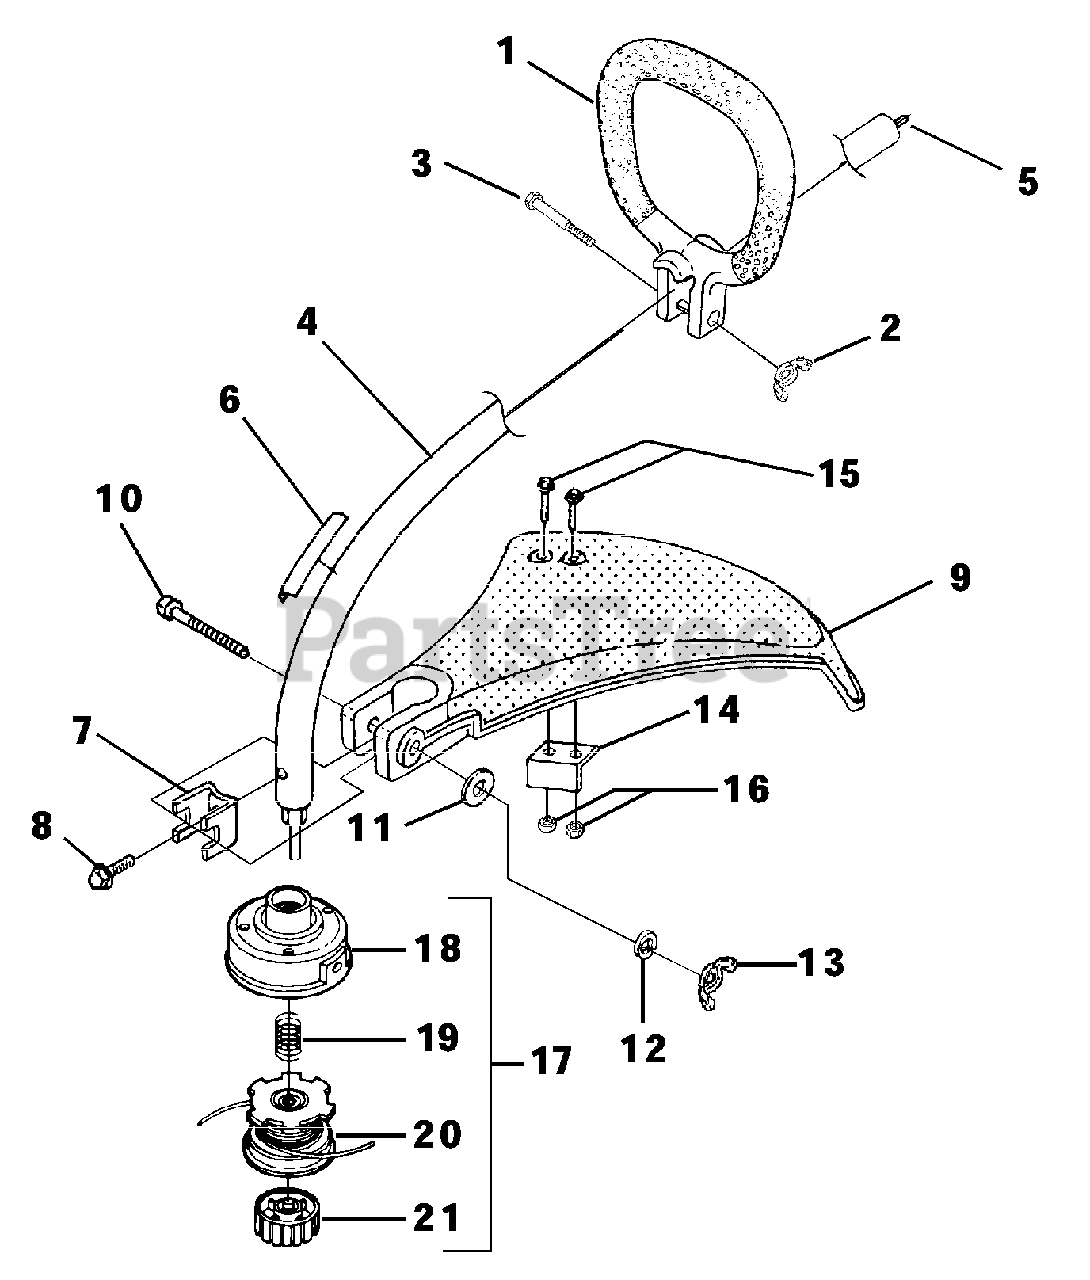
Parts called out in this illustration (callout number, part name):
1	HANDLE ASSY.-Front
2	NUT-Wing, Washer Faced (1/4-20)
3	SCREW-Cap Hex Hd.
4	DRIVESHAFT HOUSING ASSY.
5	SHAFT-Flexible
6	DECAL-Warning
7	CLAMP
8	SCREW-Sems Hex Hd. (#10-24 X 3/8")
9	DEFLECTOR & BLADE KIT (55 Deg.)
10	SCREW-Cap Hex Hd. (10-24 X 2")
11	WASHER-Flat (1/4")
12	WASHER-Lock (1/4")
13	NUT-Wing, Washer Faced (1/4-20)
14	BLADE-Cut-Off
15	SCREW-Mech. Hex Hd. (10-24 X 7/8")
16	NUT-Hex (10-24)
17	STRINGHEAD-Complete
18	HOUSING & EYELET (Dual Line)
19	SPRING-Compression
20	SPOOL & STRING (.080" Line)
21	RETAINER-Spool (R.H.Thread, Black)
